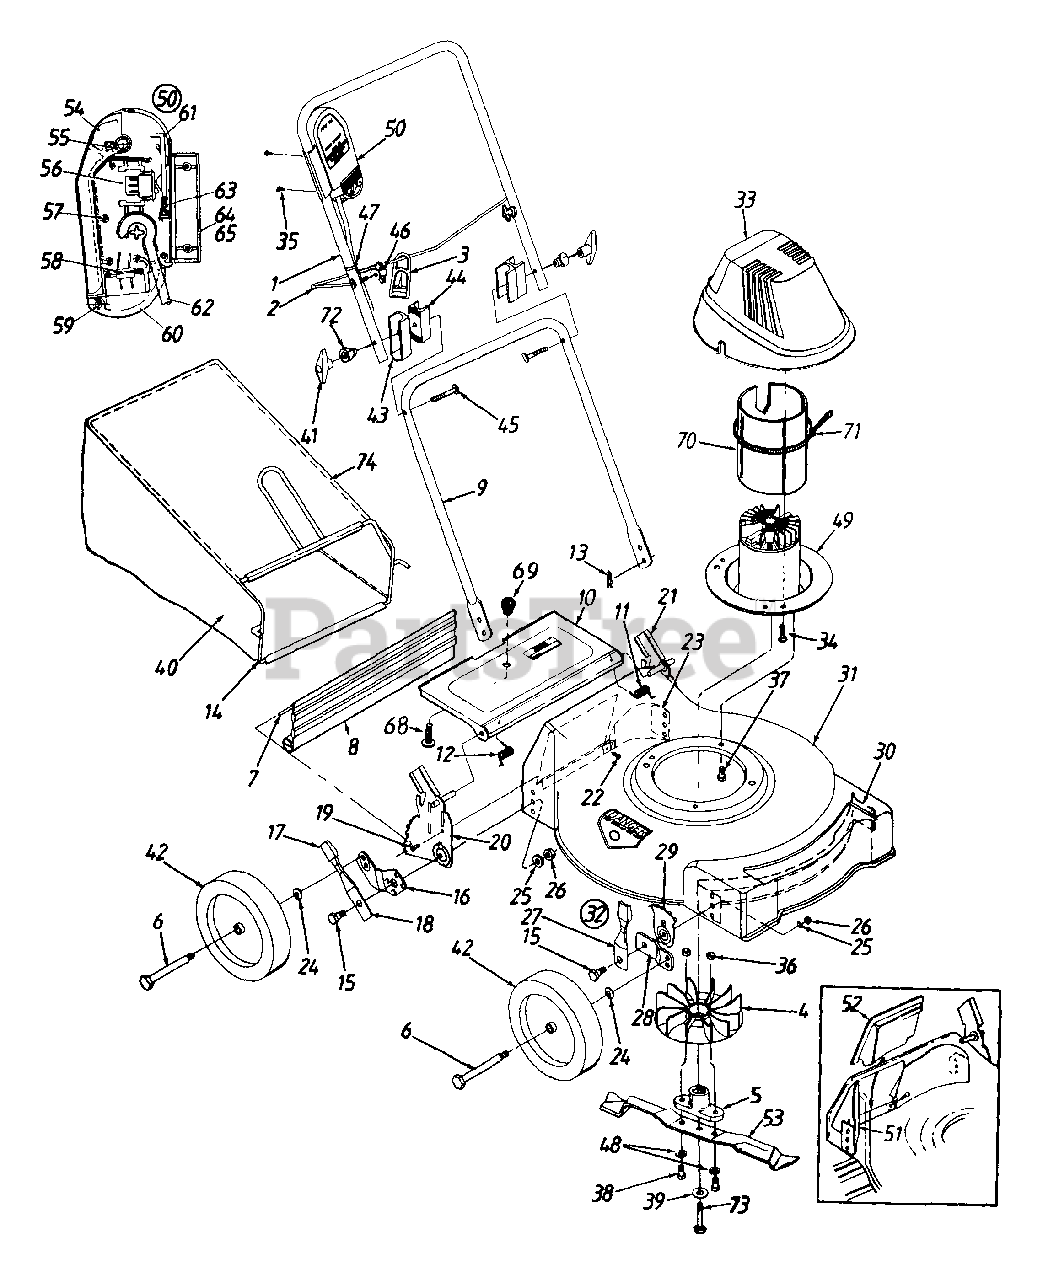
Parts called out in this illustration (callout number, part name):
3	Strain Relief - Cord
5	Blade Adapter
6	Axle Bolt
7	Rear Flap Wire
8	Rear Flap
12	Door Spring - R.H.
13	Hairpin Clip
16	Pivot Bar - R.H.
17	Spring Lever Knob
18	Spring Lever
19	Hex L-Wash. Hd. AB-Tap Scr. 1/4 x .62" Lg.
22	Torx. Mach. AB-Tap Scr. 1/4 x .62" Lg.
25	Bell-Wash..39" I.D. x 1.38" O.D.
26	Hex Nut 3/8-16 Thd.
27	Spring Lever Ass'y. w/Knob
29	Height Adj. Plate
33	Motor Cover
34	Scr. #10-16 x .75" Lg.
35	Self-Tap. Scr #7 x 1" Lg
36	Hex Nut 3/8-24 Thd.
37	Hex L-Wash. TT-Tap Scr. 3/8-16 x .75" Lg.
38	Hex Bolt 3/8-24 x 1.25" Lg.
39	Bell-Wash..396" I.D. x 1.14"
40	Grass Bag
41	Plastic Knob
42	Wheel Ass'y Comp.
43	Upper Handle Insulator
44	Lower Handle Insulator
45	Carriage Bolt 5/16-18 x 3.25"
46	Wing Nut 1/4-20 Thd.
47	Cable Tie
48	Bell-Wash. 3/8" I.D.
49	Motor, Cord & Switch Ass'y.
50	Cord & Switch Ass'y. Comp.
53	19" Blade
54	Handle - Switch Actuator
55	Spring - Switch Handle
56	Switch
57	Screw #6-32 x .5" Lg.
58	Plug Ass'y.
59	Retainer Plug Spring
60	Retainer Plug
61	Latch
62	Cord Ass'y.
63	Spring Latch
64	Housing - Upper Half
68	Truss Scr. #10-24 x .38" Lg.
70	Insulator
71	Cable Tie
72	Insulator Knob
73	Hex Bolt 3/8-24 x 2.5" Lg.
